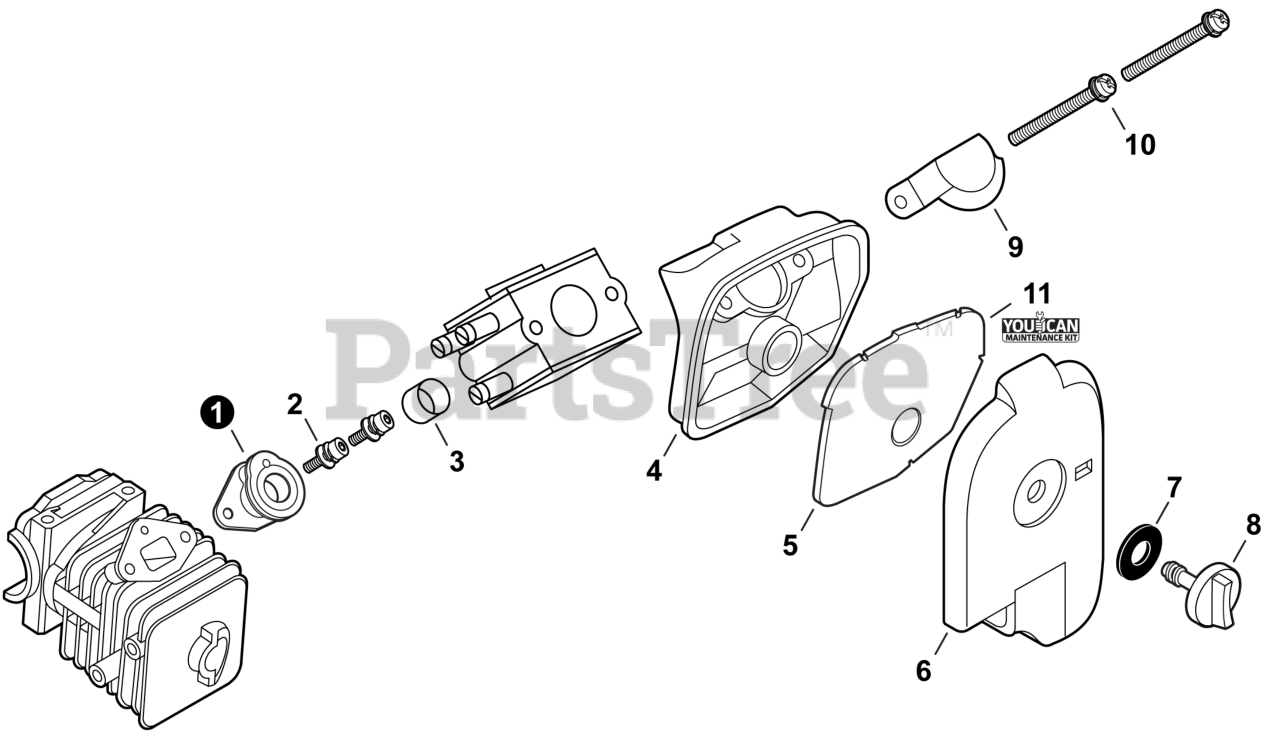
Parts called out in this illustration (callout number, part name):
1	BELLOWS, INTAKE
2	BOLT 4x12
3	COLLAR 14
4	CASE, AIR FILTER
5	FILTER, AIR
6	COVER, AIR FILTER
8	THUMBSCREW
9	PLATE, PREVENT
10	SCREW 5x50
11	TUNE-UP KIT - YOUCAN™
